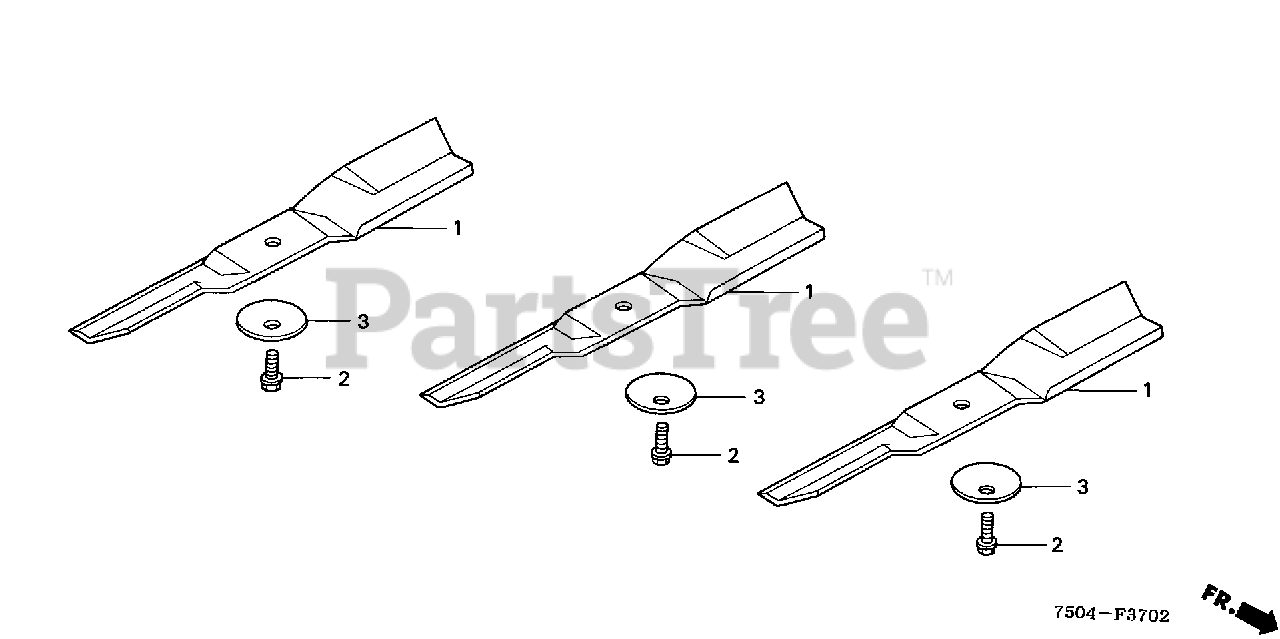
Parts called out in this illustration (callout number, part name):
1	BLADE, ROTARY
2	BOLT, BLADE HOLDER
2	BOLT, BLADE HOLDER (10X28)
3	WASHER, BLADE
